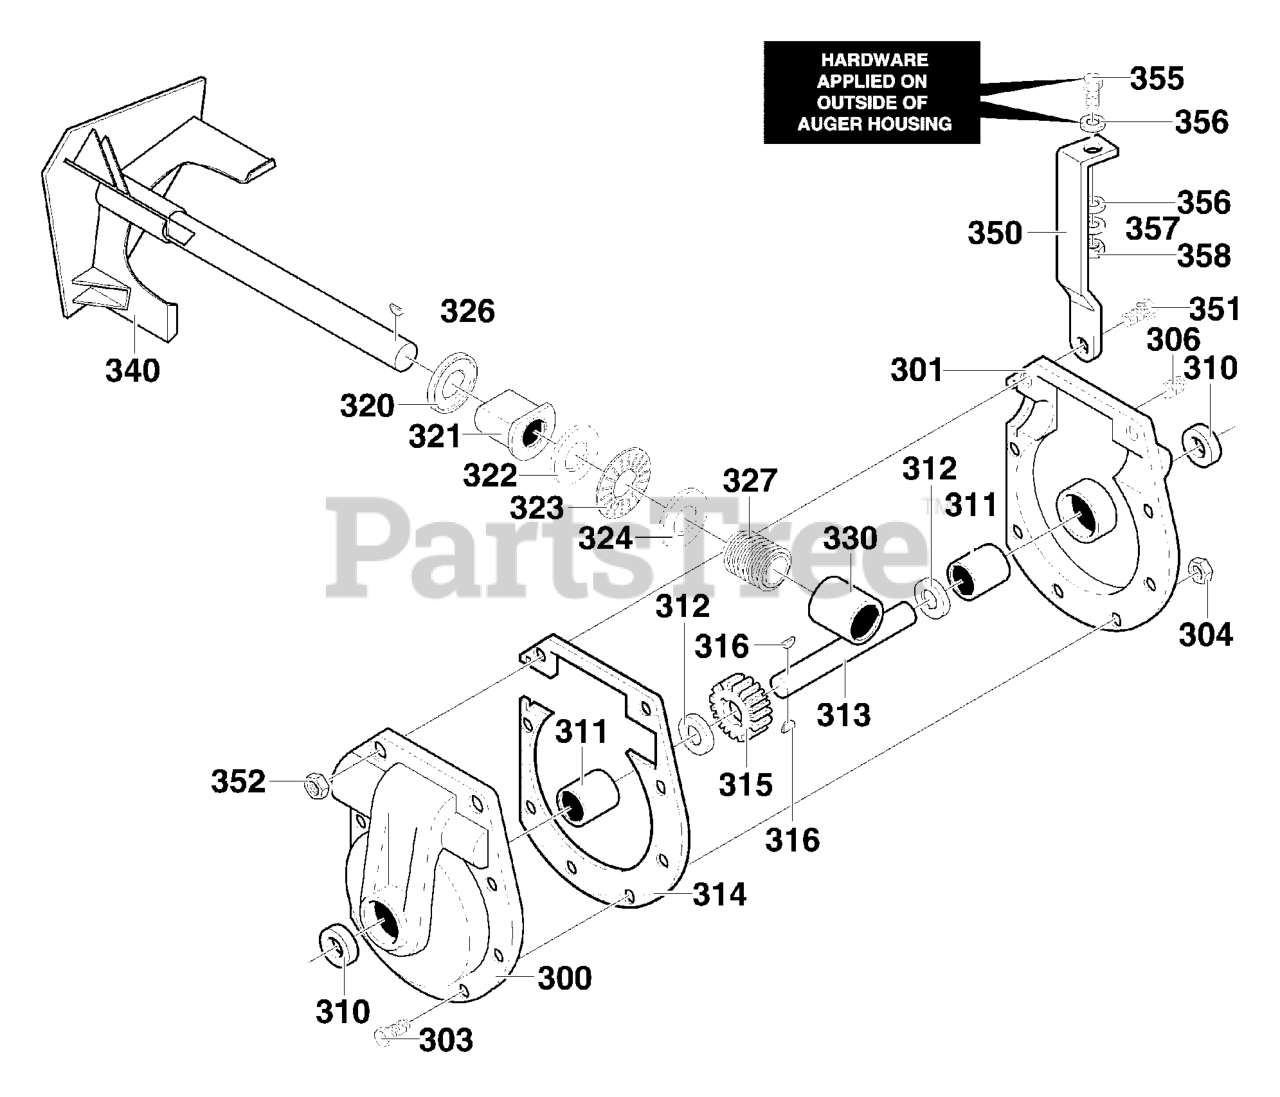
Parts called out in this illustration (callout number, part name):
300	CASE, GEAR, RH
301	CASE, GEAR, LH
303	SCREW, 5/16-24 x 1.00
304	NUT, 5/16-24
306	PIPE PLUG
310	SEAL, OIL
311	BEARING, SLEEVE
312	WASHER, FLAT 1.00 x 1.54 x .09
313	SHAFT, AUGER OUTPUT
314	GASKET, GEAR BOX
315	WORM GEAR
316	KEY, WOODRUFF #91
320	RING, QUAD
321	BEARING, FL
322	WASHER, FLAT
323	BEARING, ROLL
324	WASHER, FLAT
327	WORM GEAR
330	BEARING, SLEEVE
350	BRACE, GEAR BOX
351	SCREW 5/16-24X1.75
352	NUT, 5/16-24 HEXWDFLLK
355	SCREW, 5/16-18 x 1.25
356	WASHER, FLAT .349X.69X.066
357	WASHER, SPTLK .31X.58X.08
358	NUT, 5/16-18 REGHEX
